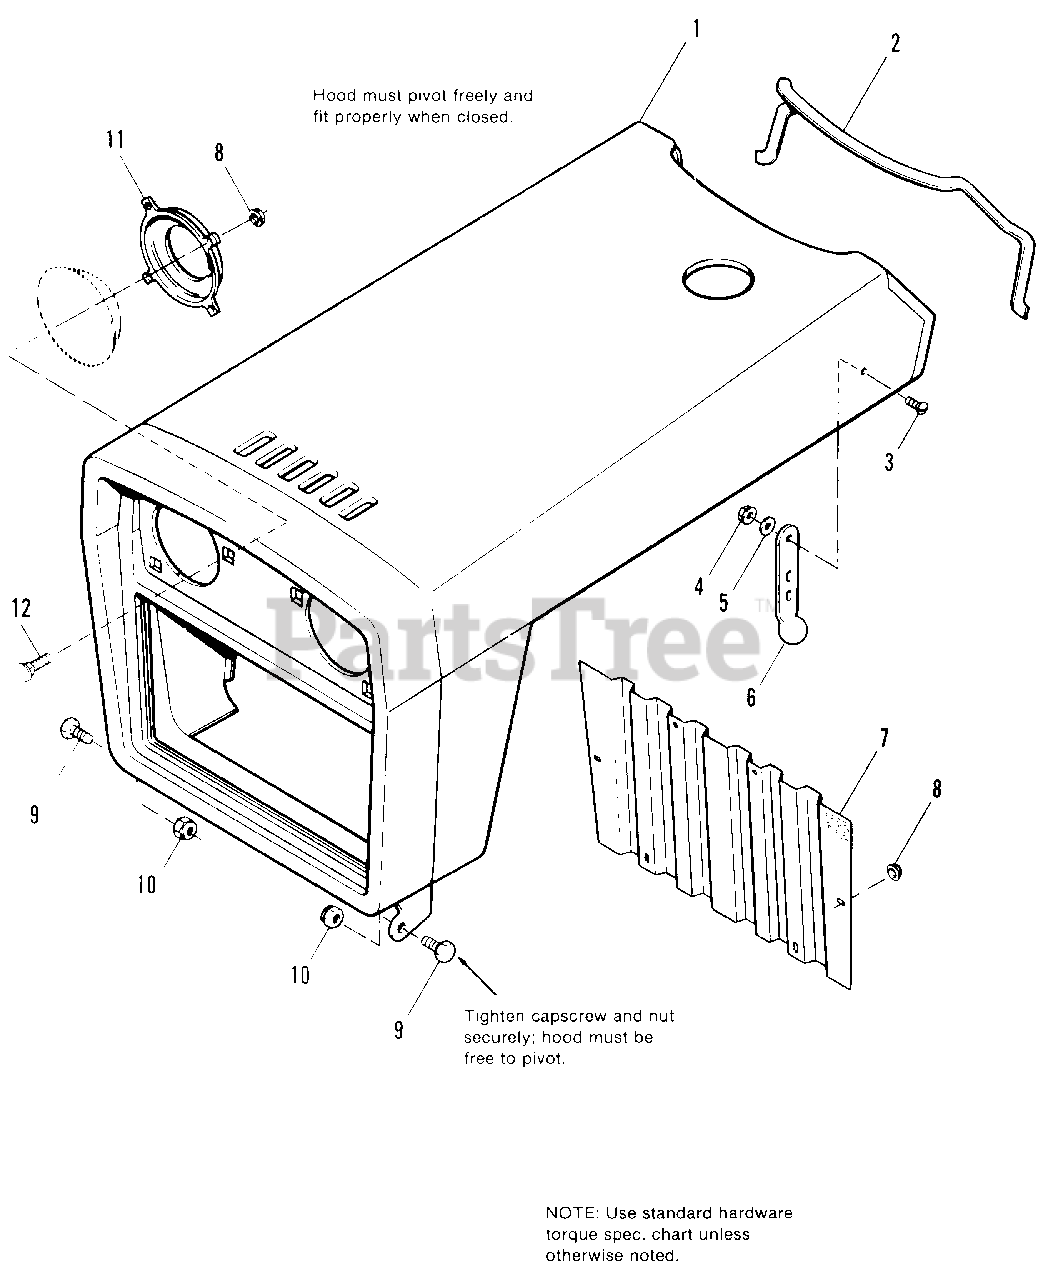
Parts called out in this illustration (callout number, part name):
1	HOOD & GRILLE ASSY.
2	MOULDING, Hood
3	SCREW, Truss Hd., #10-32 x 1/2
4	LOCKNUT, Hex, #10-32
5	WASHER, Special
6	STRAP, Hood
8	LOCKNUT, Pal
9	CAPSCREW, Hex Hd., 3/8-16 x 1
10	LOCKNUT, Hex, 3/8-16
11	BRACKET, Headlight
12	BOLT, Carriage, #10-29 x 12
